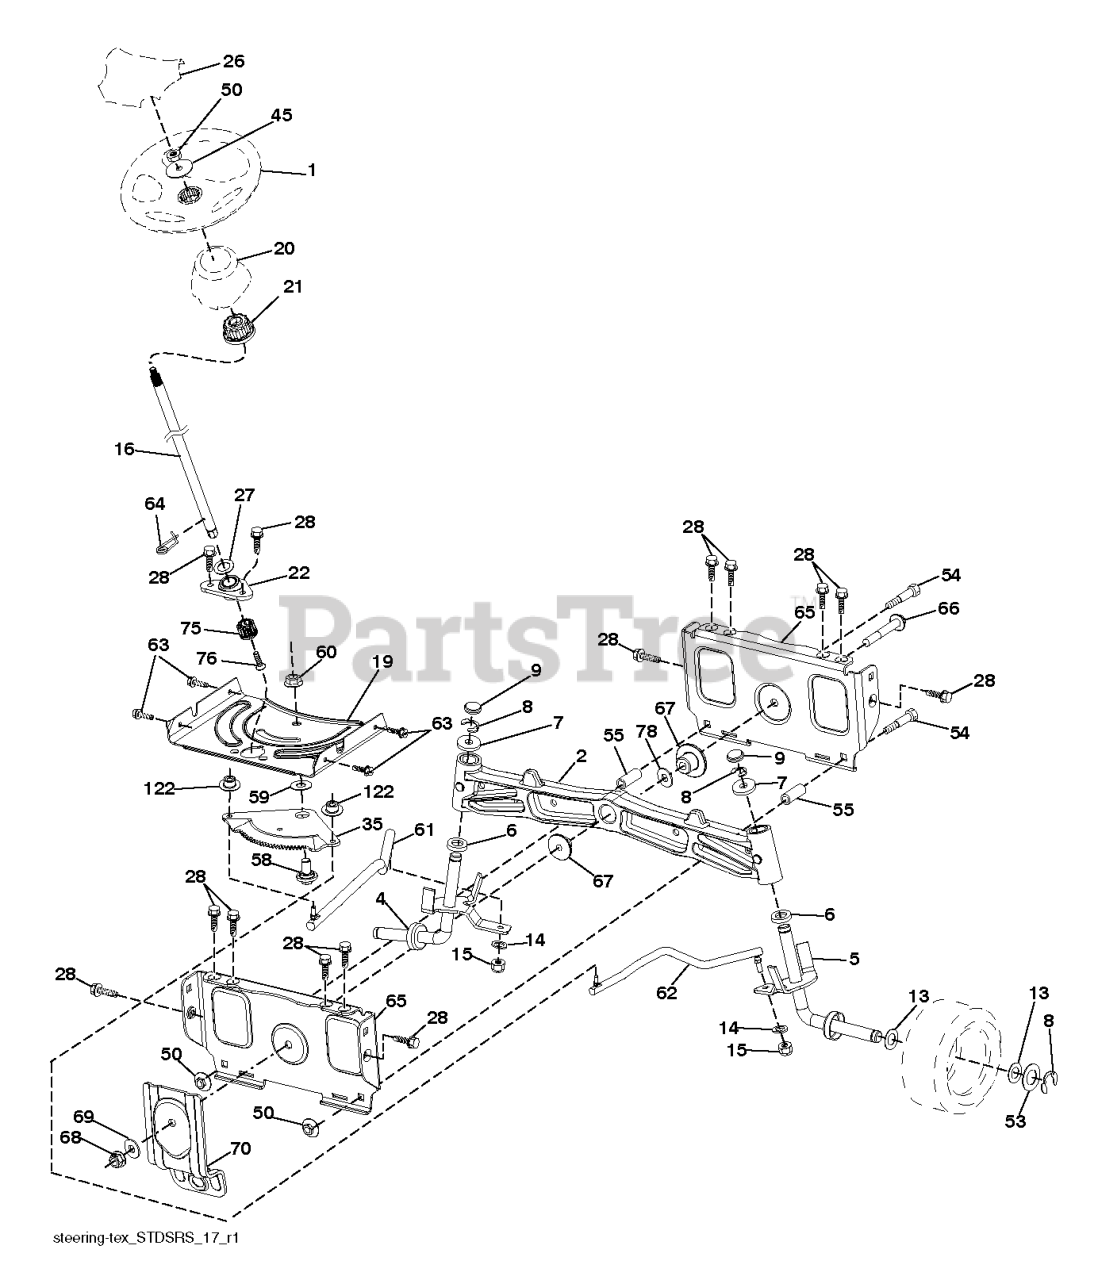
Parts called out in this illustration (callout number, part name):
1	WHEEL.STEERING.STDSRR.BLK/OV
2	AXLE.CAST.IRON
4	SPINDLE.WELDED.LH.16"TEX
5	SPINDLE.WELDED.RH.16"TEX
6	THRUST WASHER
8	RING CLIP
9	CAP.SPINDLE.BLACK
14	SLW 3/8 STD
15	NUT CROWNLOCK 3/8-24
16	SHAFT.STEER.2HIGH.SPLND.PLATED
19	PLATE.STEER.DDL.NLT/NG
20	BOOT.STRNG.PREDATOR.YT/GT.428
21	ADAPTER.WHEEL.STEER.SPLND.ALUM
22	BEARING.SHAFT.STEER.LOWER.625
26	INSERT, WHEEL STEERING
27	WASHER LT
28	SCREW, 3/8-16X3/4
35	GEAR.SECTOR.PLATE.DDL.
45	WASHER.3/8ID.2-3/8OD.12GA.PLTD
50	NUT LOCK FLG 3/8-16 UNC
53	WASHER.HARDENED
55	SPACER.BRACE.AXLE
58	BOLT.SHOULDER.SECTOR.P
59	WASHER.THURST.SECTOR.S
60	NUT FLANGE LOCK 5/8-11
61	LINK.ASM.DRAG.ADJUST.LH.PLATED
62	LINK.ASM.DRAG.ADJUST.RH.PLATED
63	SCREW
64	RETAINER.CLIP.SPRING.S
65	BRACE.AXLE.FRONT.NLT/N
66	BOLT HEX FGHD 7/16-14 X 3 SERR
67	BUSHING.PM.FRONT AXLE
68	NUT.LOCK.FLANGE.7/16
69	WASHER.1.5X.505X.118
70	BRACKET.FRT.DECK.SUSP.RR.MT431
75	PINION.ZINC PLATED
76	SCREW HEAD SOCKET LRVB
78	THRUST WASHER
122	CAP.GEAR.SECTOR.TEX
